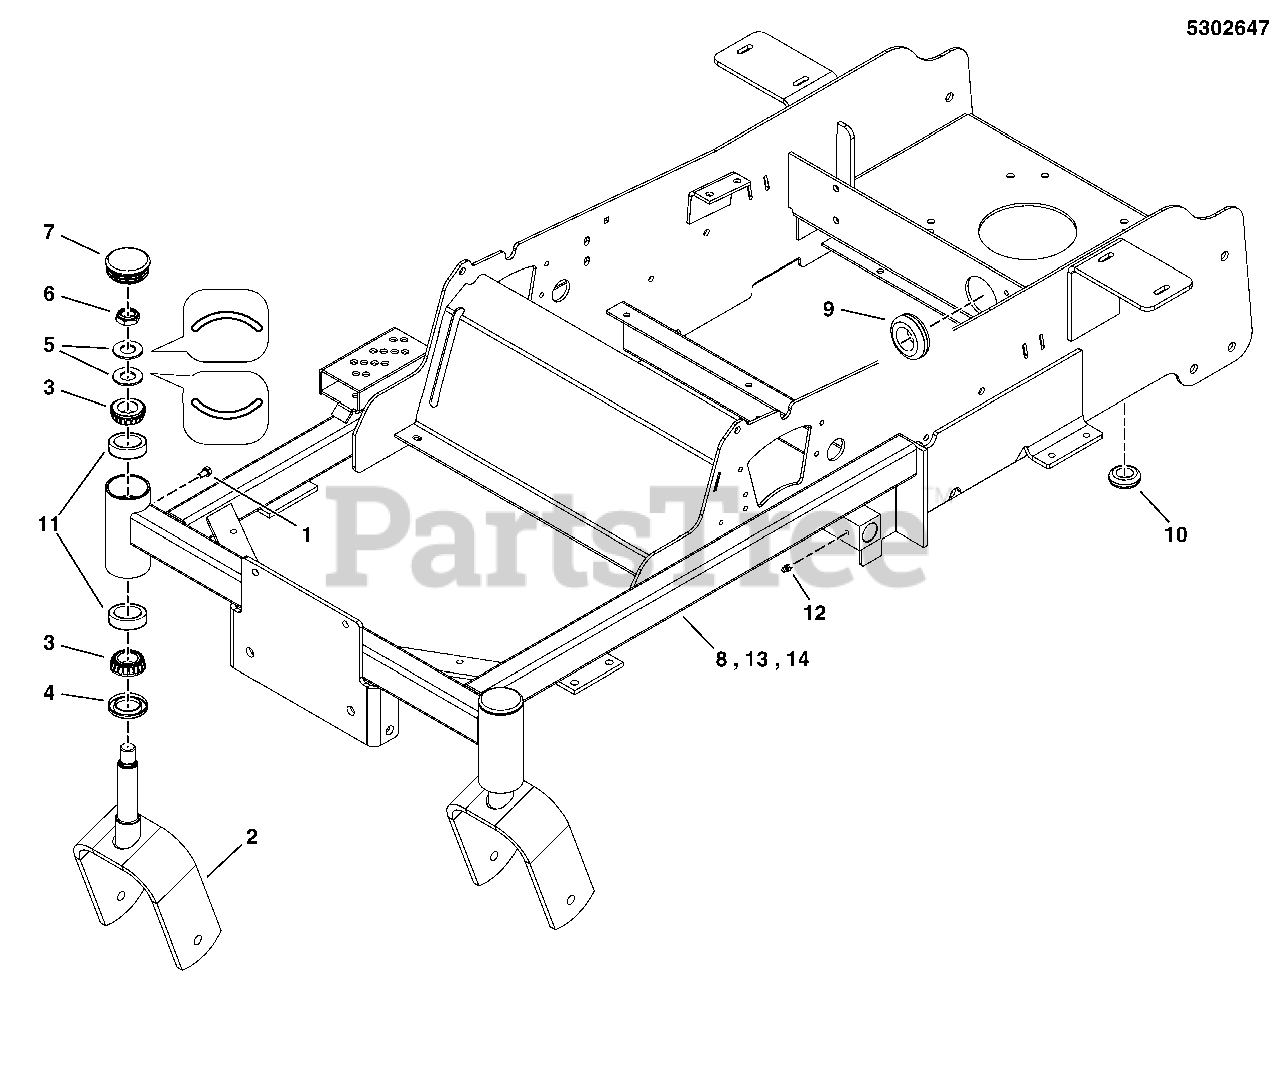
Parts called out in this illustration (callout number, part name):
1	BOLT, 1/4-28 X 1/2, GD5 YZ
2	WELD, CASTER YOKE, IS500Z
3	BEARING, TAPERED ROLLER, 1"
4	SEAL, GREASE
5	WASHER, BELLEVILLE - 1.500 X .755
6	NUT, 3/4-16, HEX JAM NYLON LOCK
7	CAP, LOW PROFILE, STEEL
8	WELD, MAIN FRAME, 48
9	GROMMET, 2" ID
10	GROMMET, 7/8
11	CUP, BEARING (SV)
12	GREASE FITTING, 1/4-28 STRAIGHT
13	WELD, FRAME, 50XT-48"
14	WELD, FRAME, 50XT-48"
